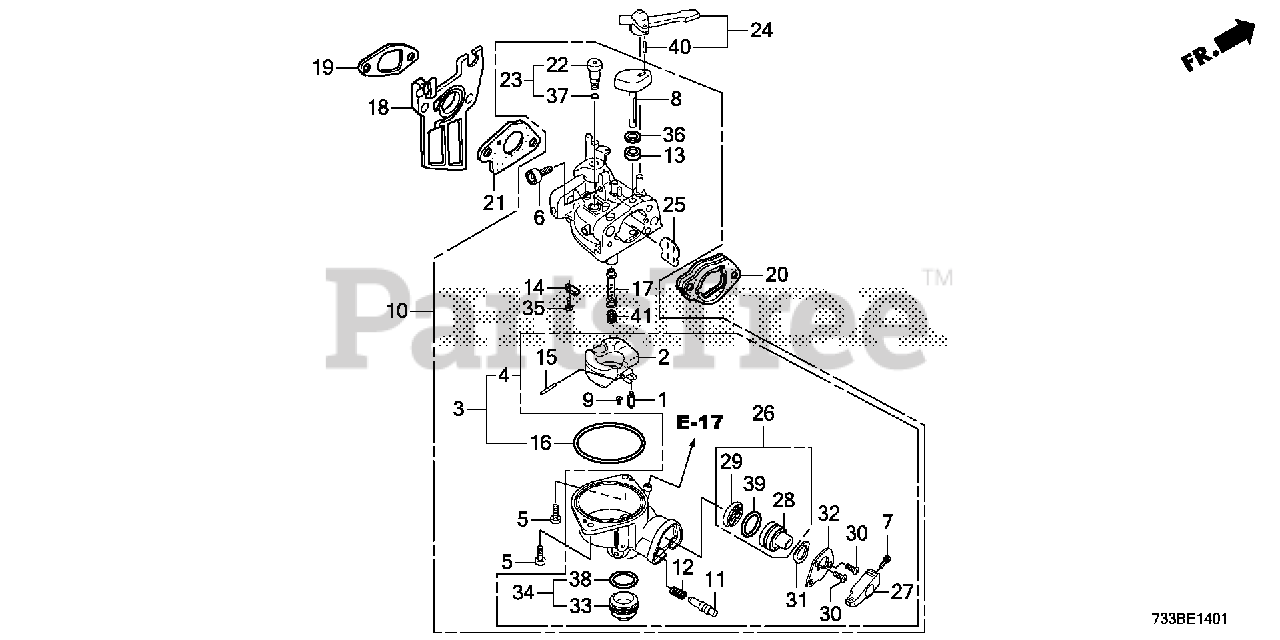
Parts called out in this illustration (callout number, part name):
1	VALVE ASSY., IN.
3	CHAMBER SET, FLOAT
4	BOWL ASSY., FUEL
6	SCREW, IDLE ADJUSTING
7	SCREW ASSY.
8	SHAFT, CHOKE
10	CARBURETOR ASSY. (LMJ 47)
14	BAFFLE, BOWL VENT
16	GASKET, FUEL BOWL
17	NOZZLE, MAIN
18	INSULATOR, CARBURETOR (JLH)
19	GASKET, INSULATOR
19	GASKET, INSULATOR (NINGBO SIL GASKET)
20	SPACER, CARBURETOR
21	GASKET, CARBURETOR
21	GASKET, CARBURETOR (NINGBO SIL GASKET)
22	JET ASSY., SLOW
23	JET SET, SLOW
24	LEVER, CHOKE (STD)
25	VALVE, CHOKE
26	VALVE SET, PETCOCK
27	LEVER, PETCOCK
28	VALVE, PETCOCK
29	SEAL, PETCOCK
31	WASHER, WAVE
32	COVER, PETCOCK
34	CUP SET, STRAINER
40	PIN, SPRING (2X12)
41	JET, MAIN (#64)
41	JET, MAIN (#66)
41	JET, MAIN (#68)
